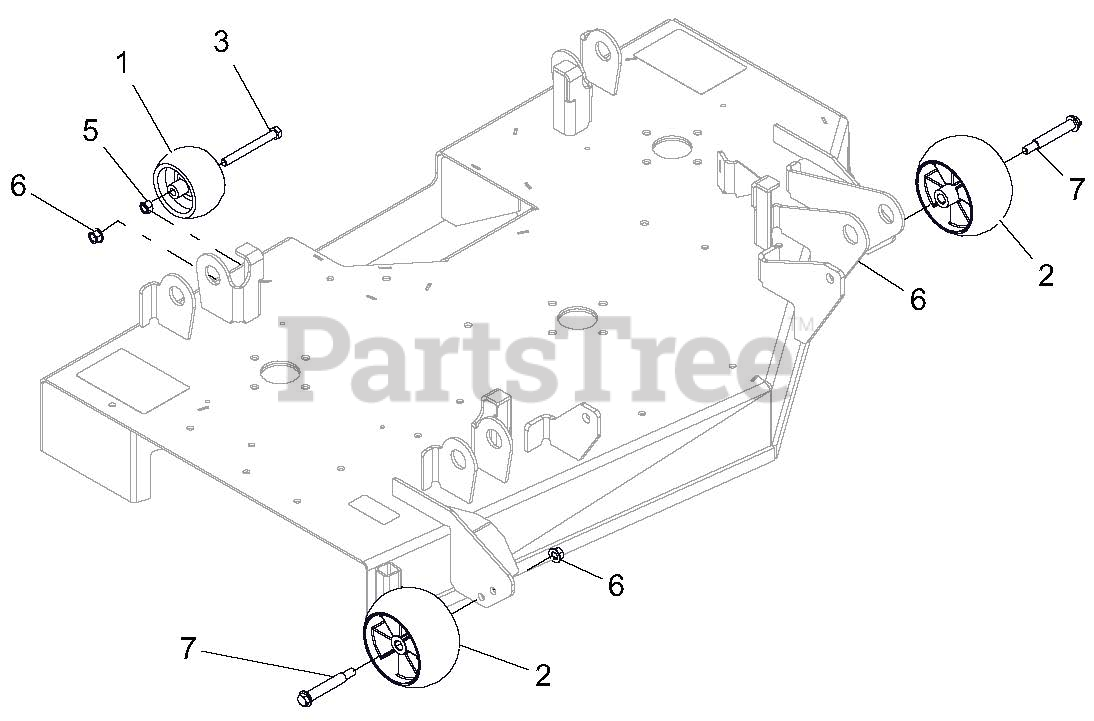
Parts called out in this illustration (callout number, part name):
2	ANTI-SCALP WHEEL - 5XOS
3	BLT-HEX .38-16X3.50 GR5 YWZC
5	NUT-HEX .38-16 YWZC
6	NUT, LK-TOP-FLG .38-16 YWZC
7	BLT-SHLDR .38-16X2.50 HWH G5YZ
